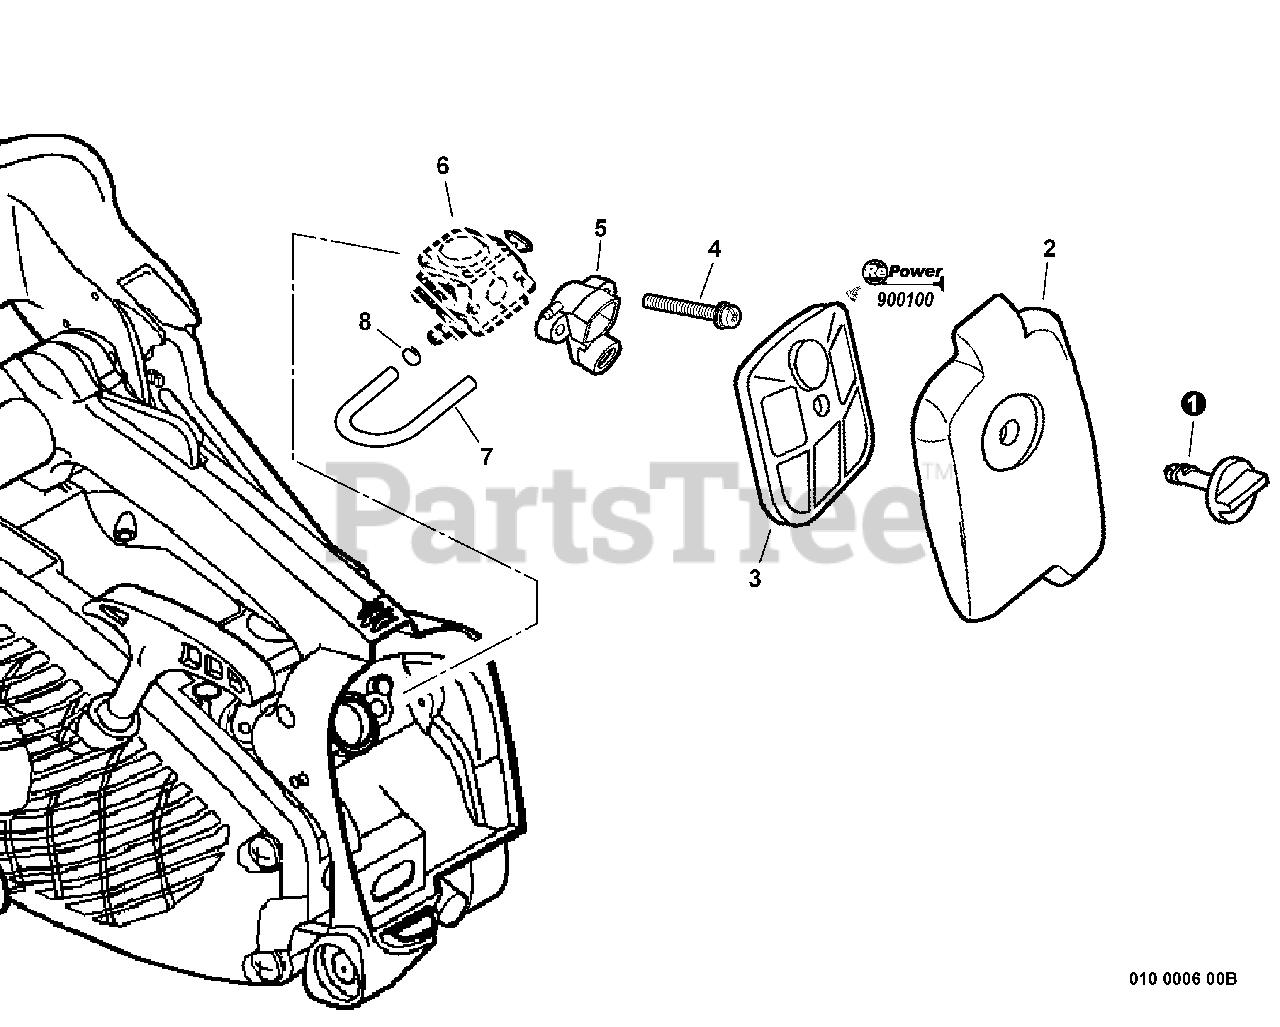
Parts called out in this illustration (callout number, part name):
1	THUMBSCREW
2	COVER, AIR FILTER
3	FILTER, AIR
4	SCREW 5×50
5	ADAPTOR, AIR FILTER
6	CARBURETOR
7	PIPE 3×6×80 BLACK
8	CLIP 6 MM
9	REPOWER TUNE-UP KIT
